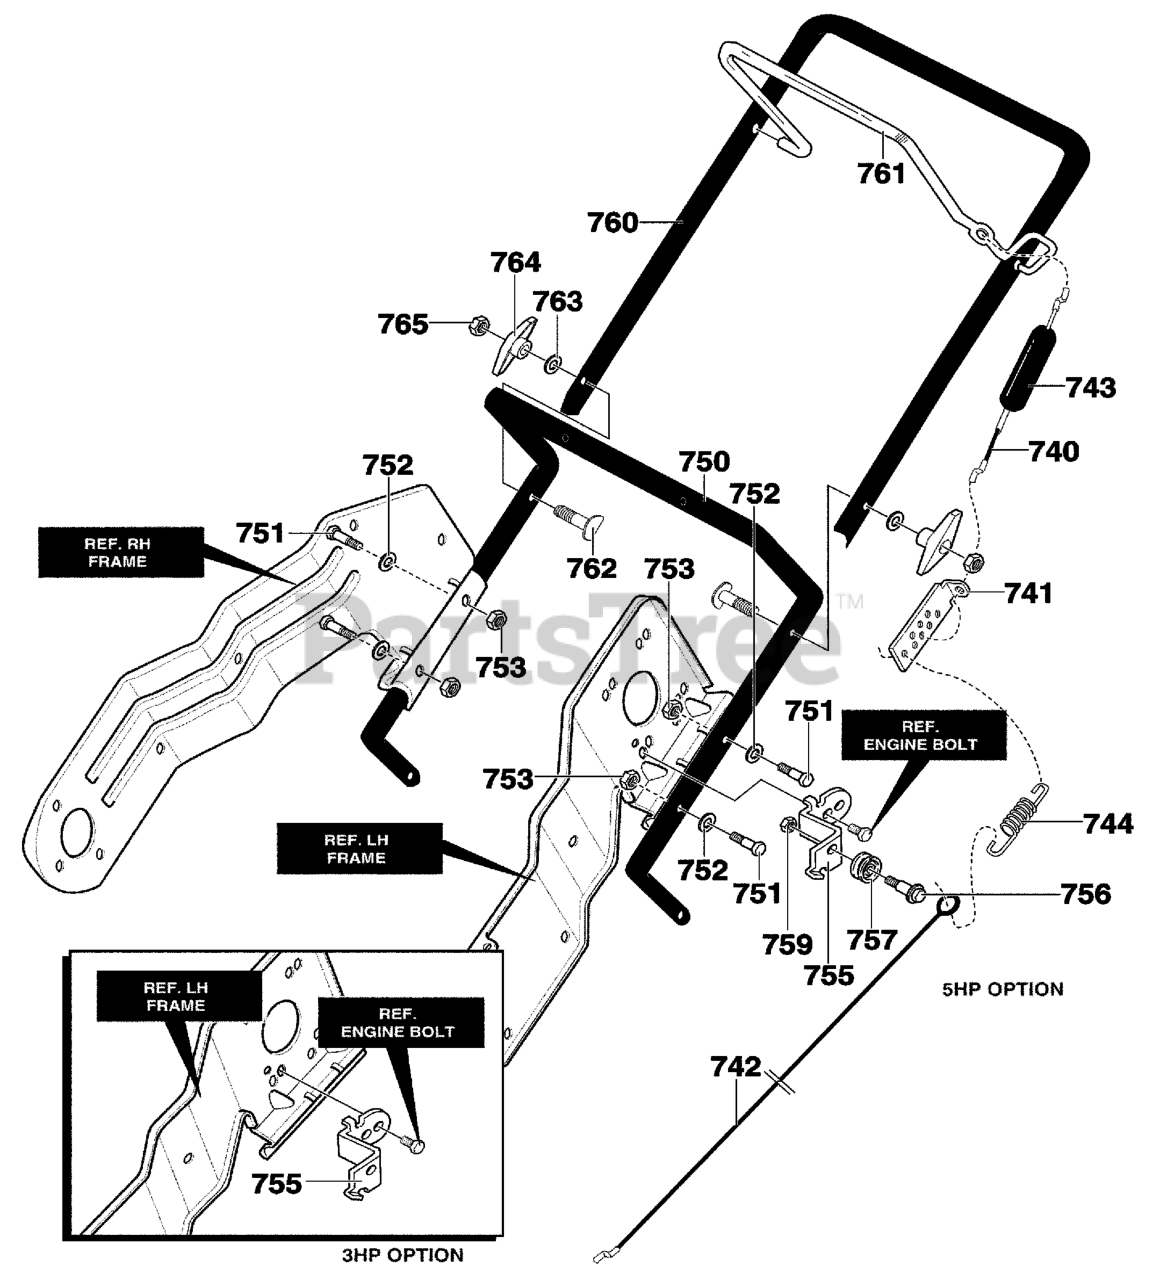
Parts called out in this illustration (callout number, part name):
740	CABLE, UPPER
741	BRKT, CABLE ADJ
742	CABLE LOWER CONTROL
743	BOOT, CLUTCH SPRING
750	HANDLE LOWER
751	SCREW, 1/4-20X1.25
752	WASHER, FLAT .281X.63X.065
753	NUT, 1/4-20
755	BRACKET, CABLE
756	BOLT, .375X.375 1/4-20
757	PULLEY, .906X.305
759	NUT, 1/4-20
760	HANDLE, UPPER
761	BAIL, CONTROL
762	BOLT, 5/16-18X2.00
763	WASHER, FORM
764	KNOB,T
765	NUT, 5/16-18
